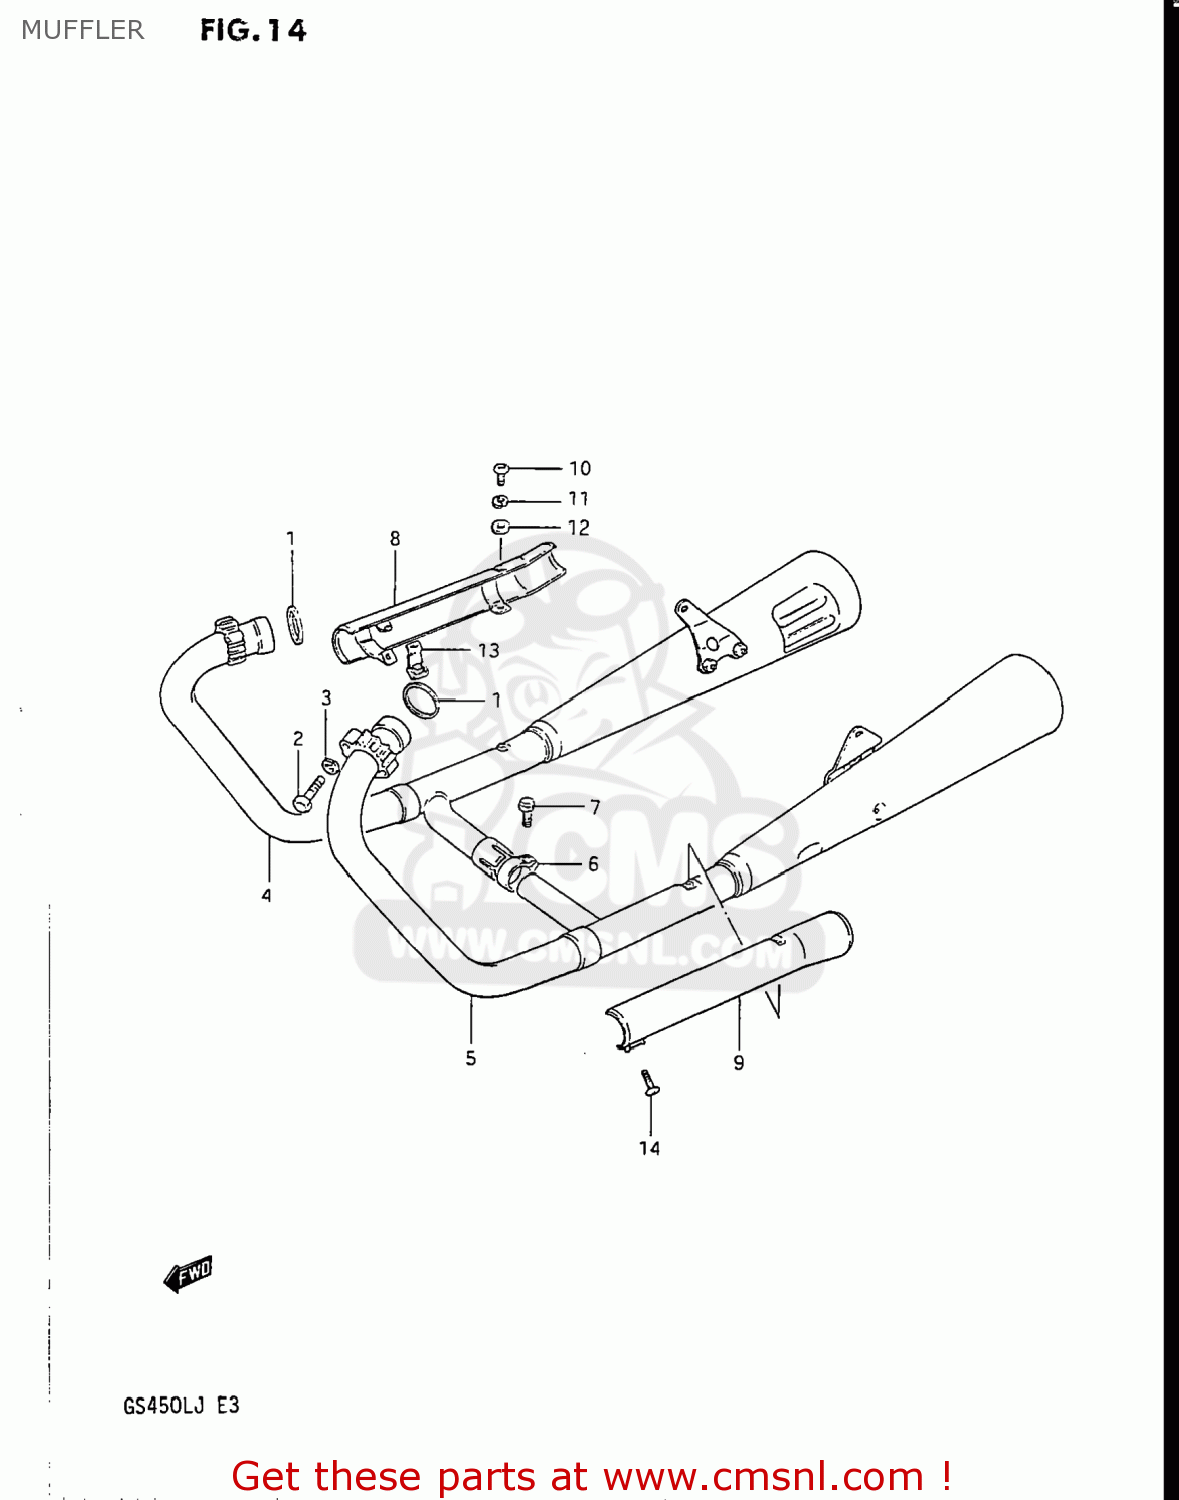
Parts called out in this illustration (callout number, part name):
1	GASKET,EXHAUST PIPE (NAS)
2	BOLT 8X40
3	LOCK WASHER
4	MUFFLER ASSEMBLY
5	MUFFLER ASSEMBLY
6	CLAMP
7	BOLT
8	COVER,MUFFLER,RIGHT
9	COVER,MUFFLER LH
10	SCREW
11	WASHER,LOCK
12	WASHER
13	CLAMP,MUFFLER COVER
14	SCREW
